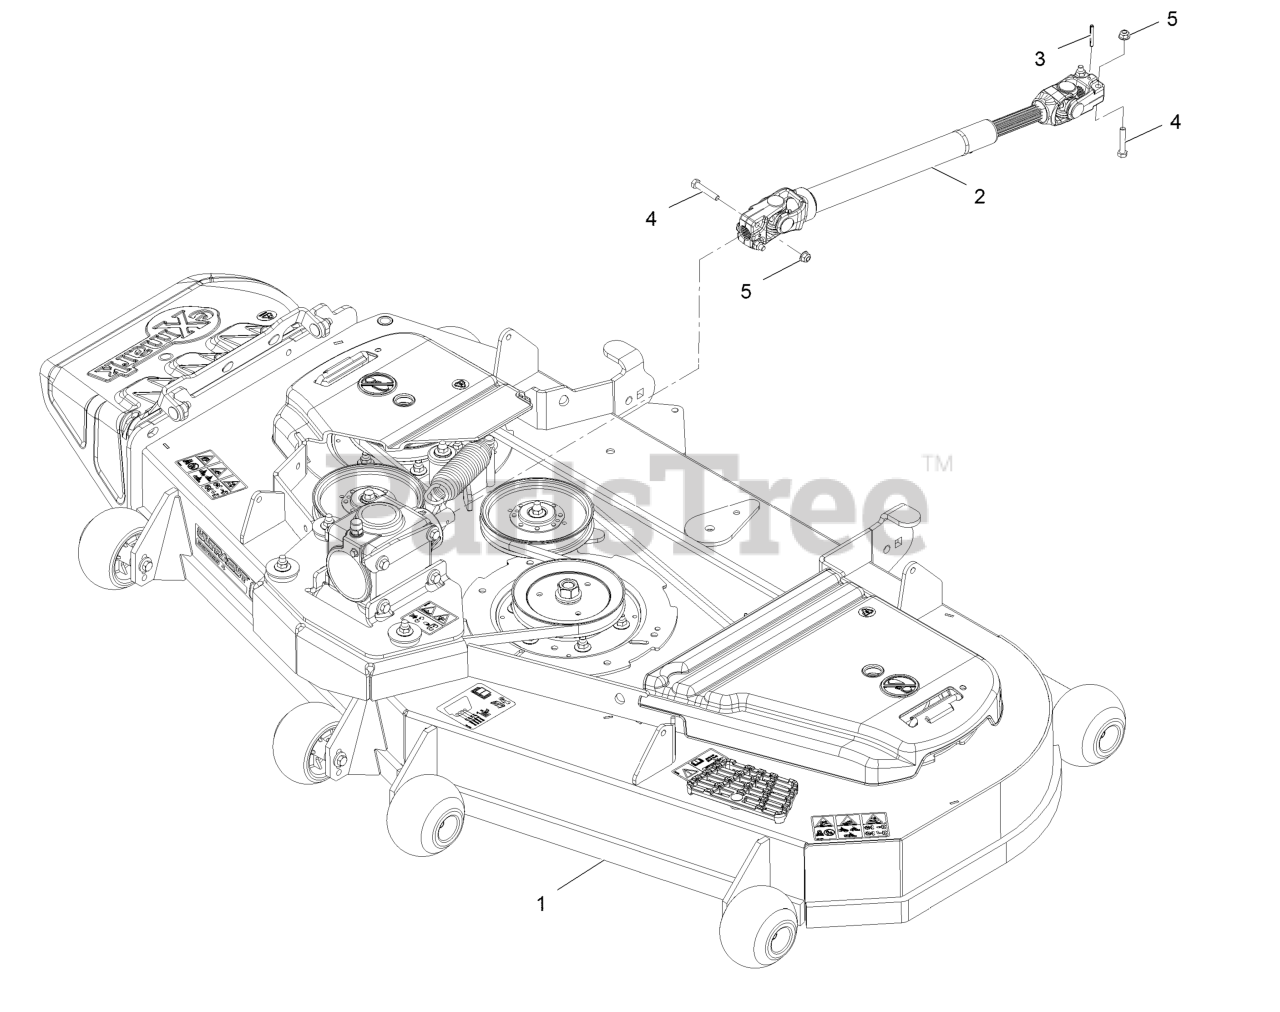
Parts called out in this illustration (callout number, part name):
1	Deck ASM-604
2	Driveshaft ASM
3	Pin-Roll
4	Screw-HH 5/16-18 X 1 3/4
5	Nut-Nyloc 5/16-18 Flg
